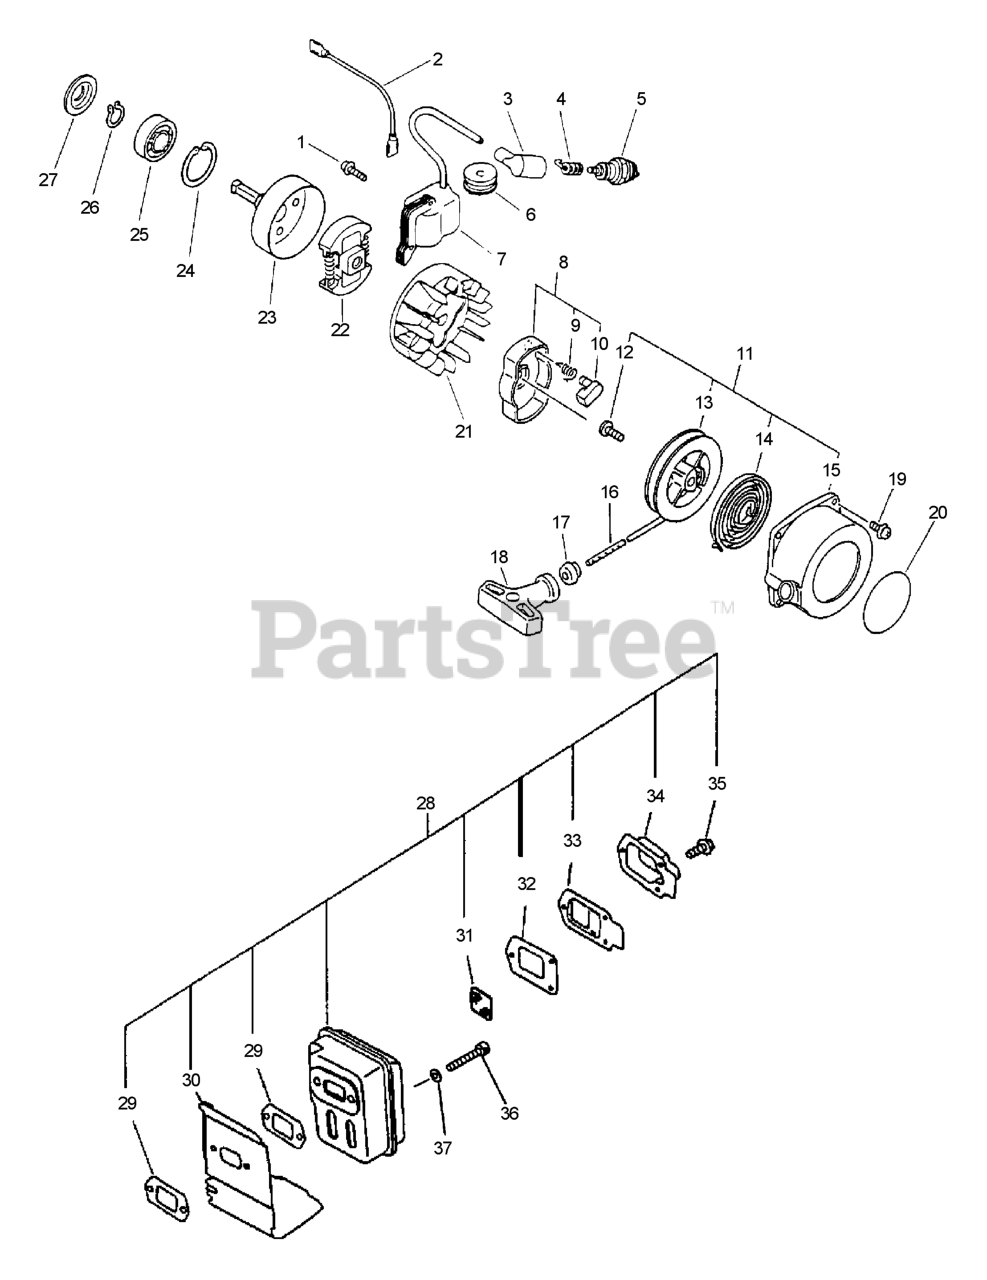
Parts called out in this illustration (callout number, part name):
1	SCREW - 4X22
2	LEAD - GROUND
3	CAP, SPARK PLUG
4	TERMINAL, SPARK PLUG CAP
5	SPARK PLUG -- BPM-7Y
5	SPARK PLUG -- BPMR-7A
6	GROMMET
7	COIL, IGNITION
8	STARTER PAWL ASSY
9	SPRING, RETURN
10	PAWL, STARTER - BLACK
11	STARTER ASSY
13	REEL, ROPE
14	SPRING, REWIND
15	CASE, STARTER
16	ROPE, STARTER
17	GUIDE, ROPE
18	GRIP, STARTER
19	SCREW - 4X16
20	LABEL - ECHO
21	FLYWHEEL
22	CLUTCH ASSY
23	DRUM, CLUTCH
24	RING, RETAINING - 32
25	BEARING, BALL - 6201
26	RING, RETAINING - 12
27	RETAINER, PIPE
28	MUFFLER ASSY
29	GASKET, EXHAUST
30	COVER, EXHAUST
31	SCREEN, SPARK ARRESTOR
32	GASKET, EXHAUST
33	GASKET, EXHAUST - INNER
34	GUIDE, EXHAUST - OUTER
35	SCREW - 4X10
36	SCREW - 5X55
37	WASHER - 5
